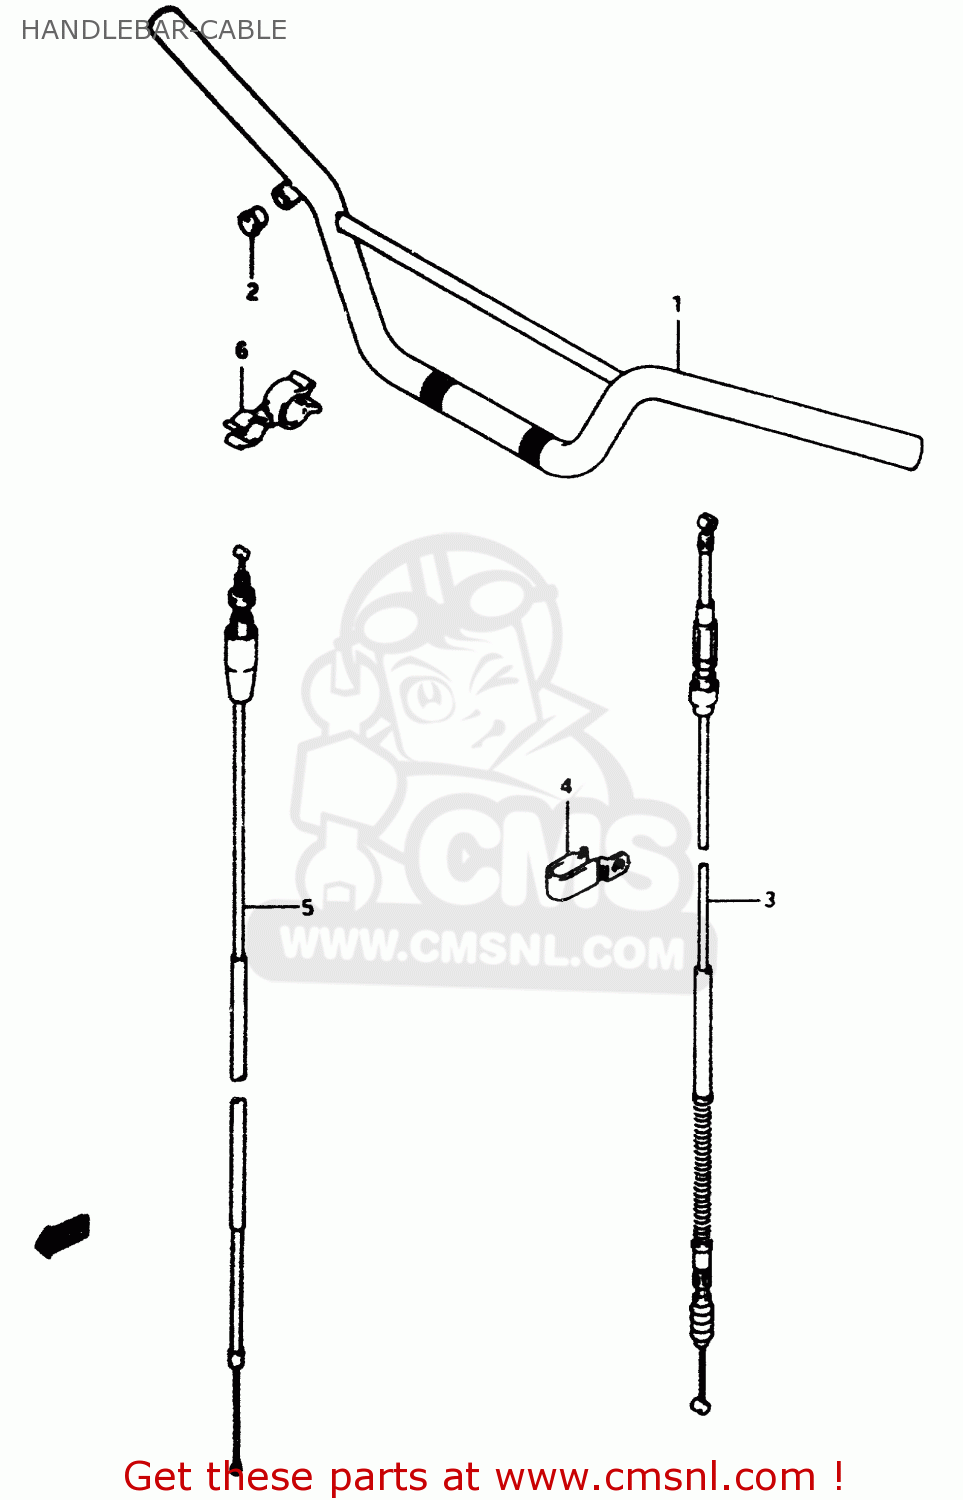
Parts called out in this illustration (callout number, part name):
1	HANDLEBAR COMP
2	CAP(OD:14)
3	CABLE ASSY,CLUTCH
4	CLAMP
5	CABLE ASSY,THROTTLE
6	CLAMP
